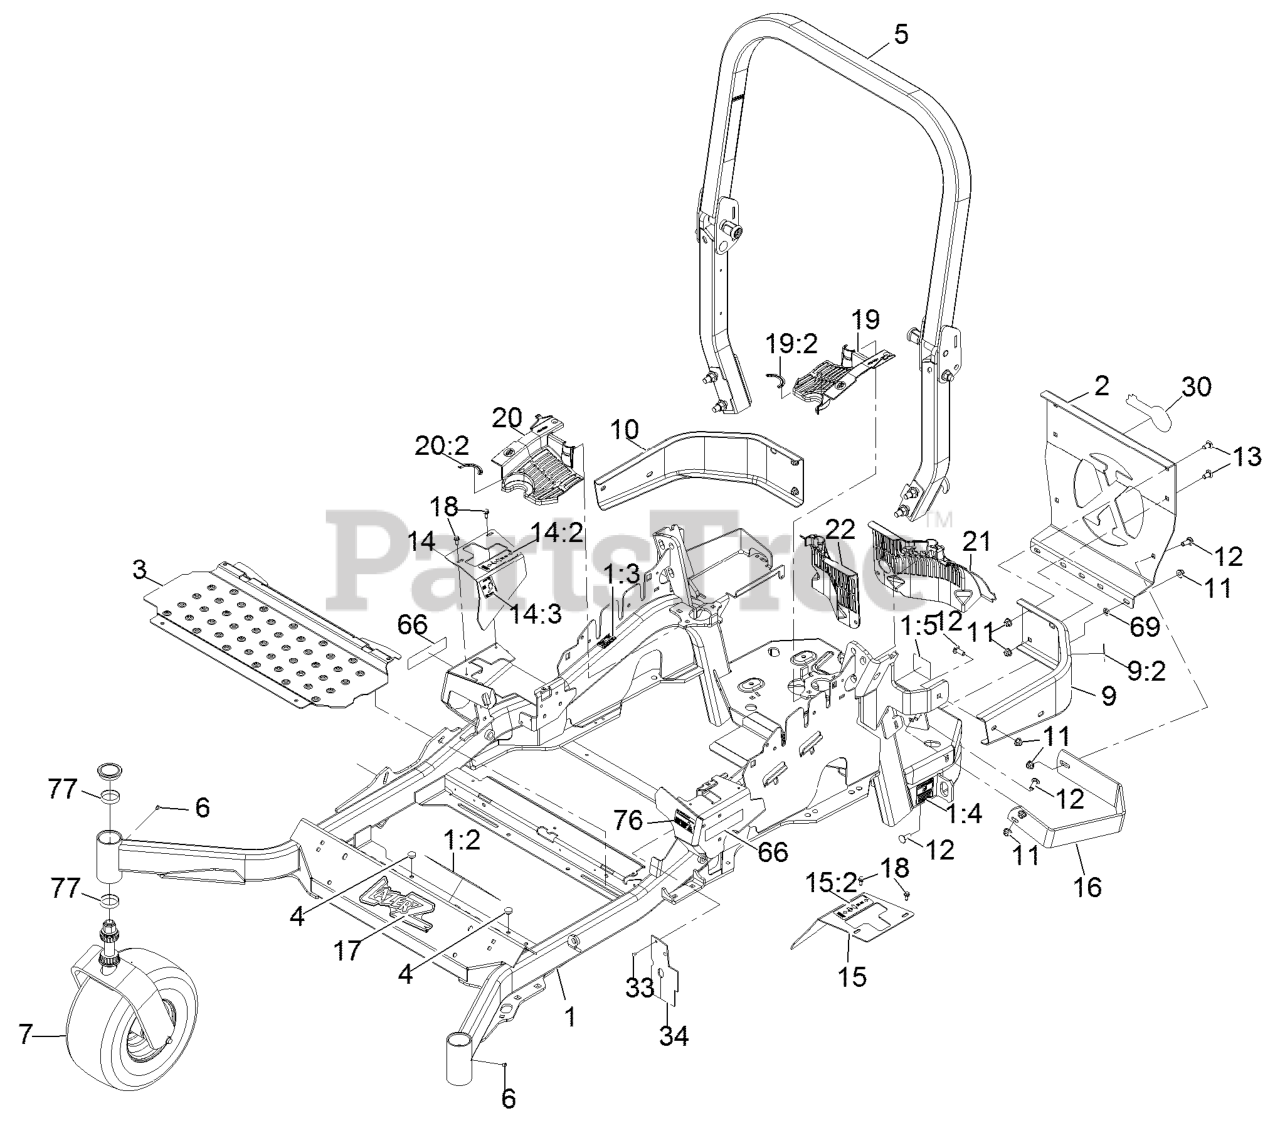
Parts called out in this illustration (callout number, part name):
1	MAINFRAME ASM
1:2	DECAL-SLOPE
1:3	DECAL-CAUTION
1:4	DECAL-BELT DRIVE
1:5	DECAL-SPARK ARRESTER
2	PLATE,REAR GUARD
5	ASM,ROPS SERVICE EXMARK
7	Front Caster And Fork Asm
9	LH BUMPER ASM
9:2	DECAL-CAUTION
10	BUMPER-RH
11	NUT-HF, NI
12	SCREW-CARR
13	SCREW-CARR
14	RH MOTION CONTROL COVER ASM
14:2	DECAL-MOTION CONTROL
14:3	DECAL-PARK BRAKE
15	LH MOTION CONTROL COVER ASM
15:2	DECAL-MOTION CONTROL
16	GUARD-MUFFLER
17	DECAL,LAZER MODEL
18	SCREW-HWH
19	LH HYDRO GUARD ASM
19:2	DECAL-HYDRO OIL
20	RH HYDRO GUARD ASM
20:2	DECAL-HYDRO OIL
21	GUARD-HYDRO, REAR (LH)
22	GUARD-HYDRO, REAR (RH)
33	RIVET-POP
34	DEFLECTOR-AIR FLOW
66	DECAL-S-SERIES
69	NUT-PUSH
76	DECAL-FUEL FILL
77	CUP-BEARING
